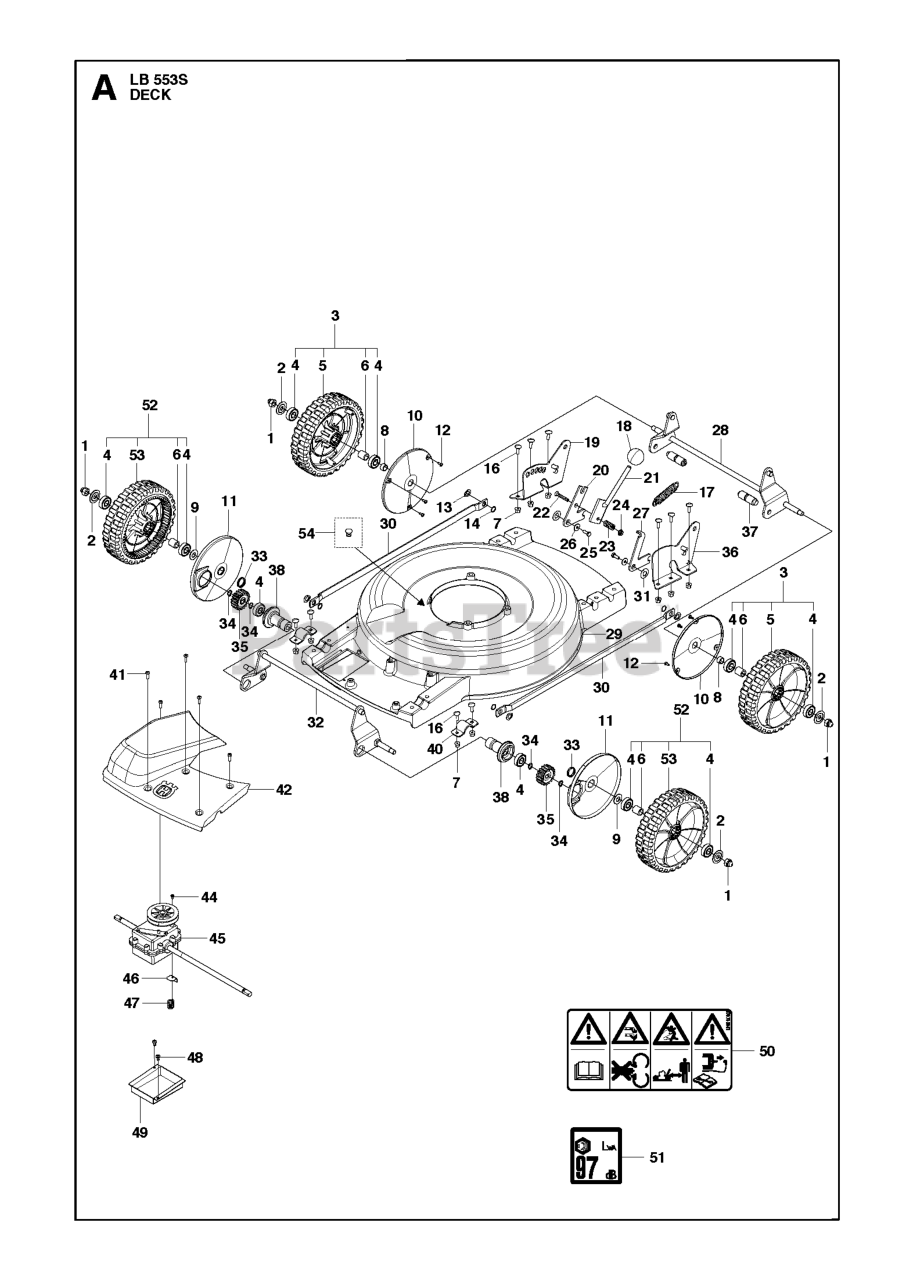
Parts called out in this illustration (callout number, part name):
1	CLUTCH COVER
4	CHAIN GUIDE
9	COVER, CHAIN BRAKE
11	WEAR GUARD, CHAIN
12	BRAKE BAND
15	WORM WHEEL
18	LABEL 400 SERIES
19	NUT M8 FLANGE
